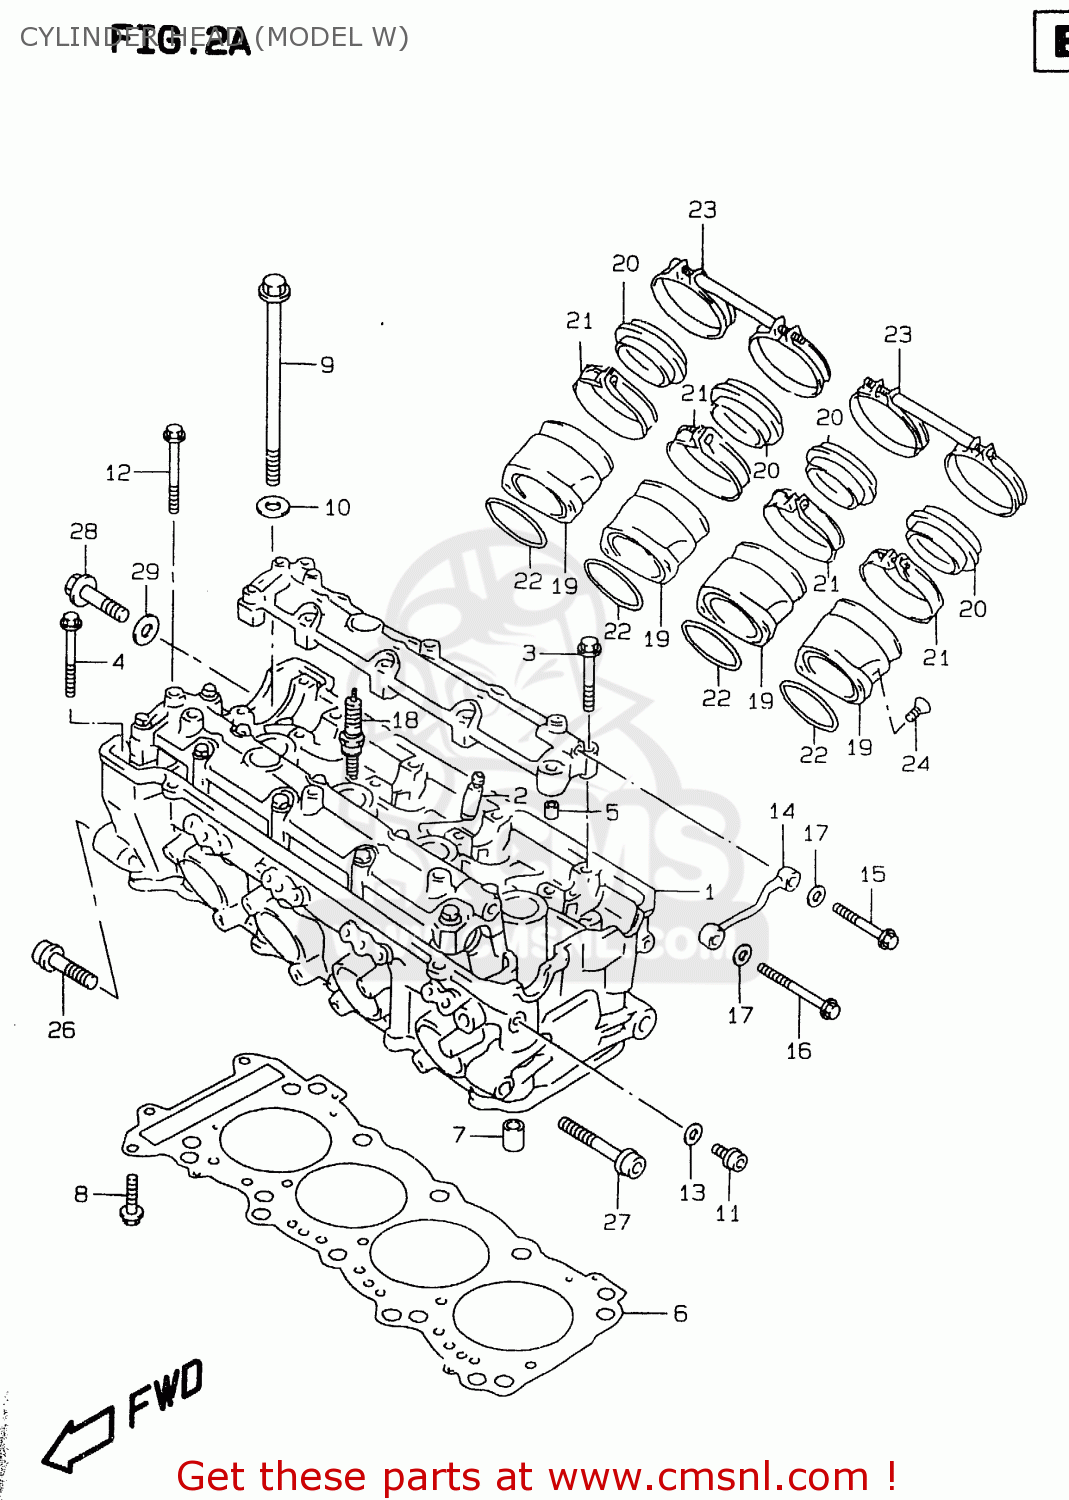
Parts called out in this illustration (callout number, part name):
1	HEAD ASSY,CYLINDER
2	GUIDE,VALVE
3	BOLT(6X39)
4	BOLT(6X45)
5	PIN(6.2X8X16)
6	GASKET,CYLINDER HEAD (T
7	PIN
8	BOLT
9	BOLT(10X160)
10	WASHER(10.5X19X2)
11	BOLT
12	BOLT,CYL.OIL P
13	GASKET(5.8X13X1.2) (NAS)
14	PIPE,CYLINDER HEAD OIL
15	BOLT
16	BOLT (6X45)
17	WASHER
18	PLUG,SPARK(CR8E)
19	PIPE,INTAKE NO.1
20	PIPE,INTAKE NO.2
21	CLAMP
22	O RING(D:2.4,ID:44)
23	CLAMP,INTAKE PIPE
24	BOLT(6X16)
25	BOLT
26	BOLT
27	BOLT,CYL HEAD SIDE FACE
28	WASHER,HEAD COVER
